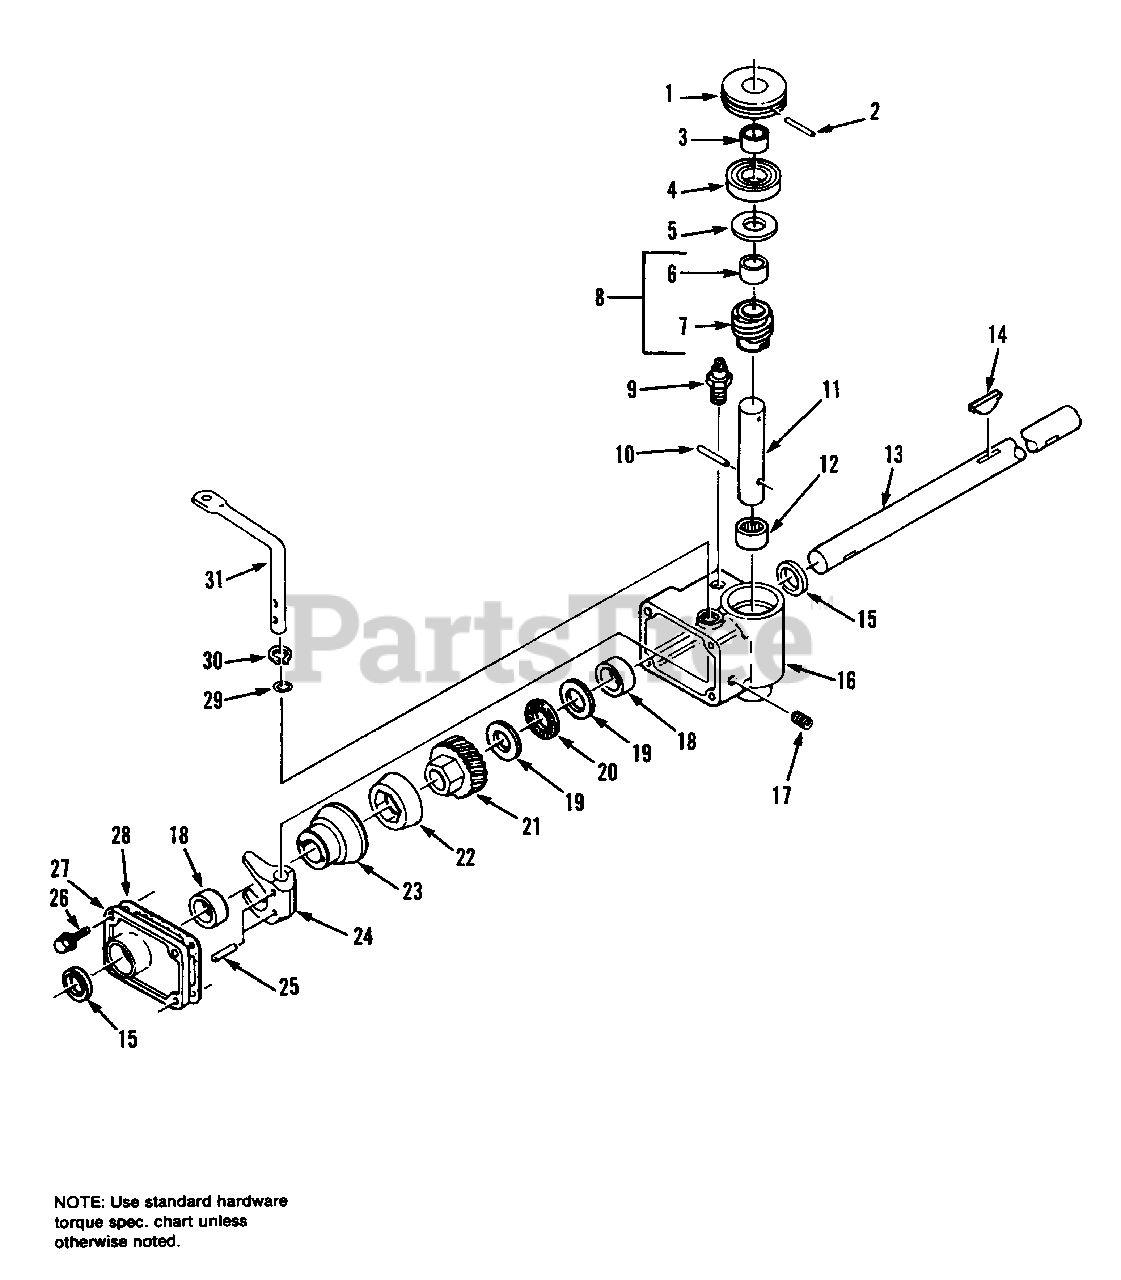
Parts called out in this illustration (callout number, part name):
8	WORM GEAR ASSY. (Incl. Ref. Nos. 6 & 7)
11	SHAFT, Worm
12	BEARING, Needle
13	SHAFT, Drive
16	GEAR REDUCER ASSY. (Incl. Ref. Nos. 12, 15 & 18)
19	RACE, Bearing
20	BEARING, Thrust
22	CONE, Friction
23	DRUM, Clutch
24	FORK, Shift
26	SCREW
27	COVER, Gear Box (Incl. Ref. Nos. 15 & 18)
30	SNAP RING
31	LEVER, Shift
